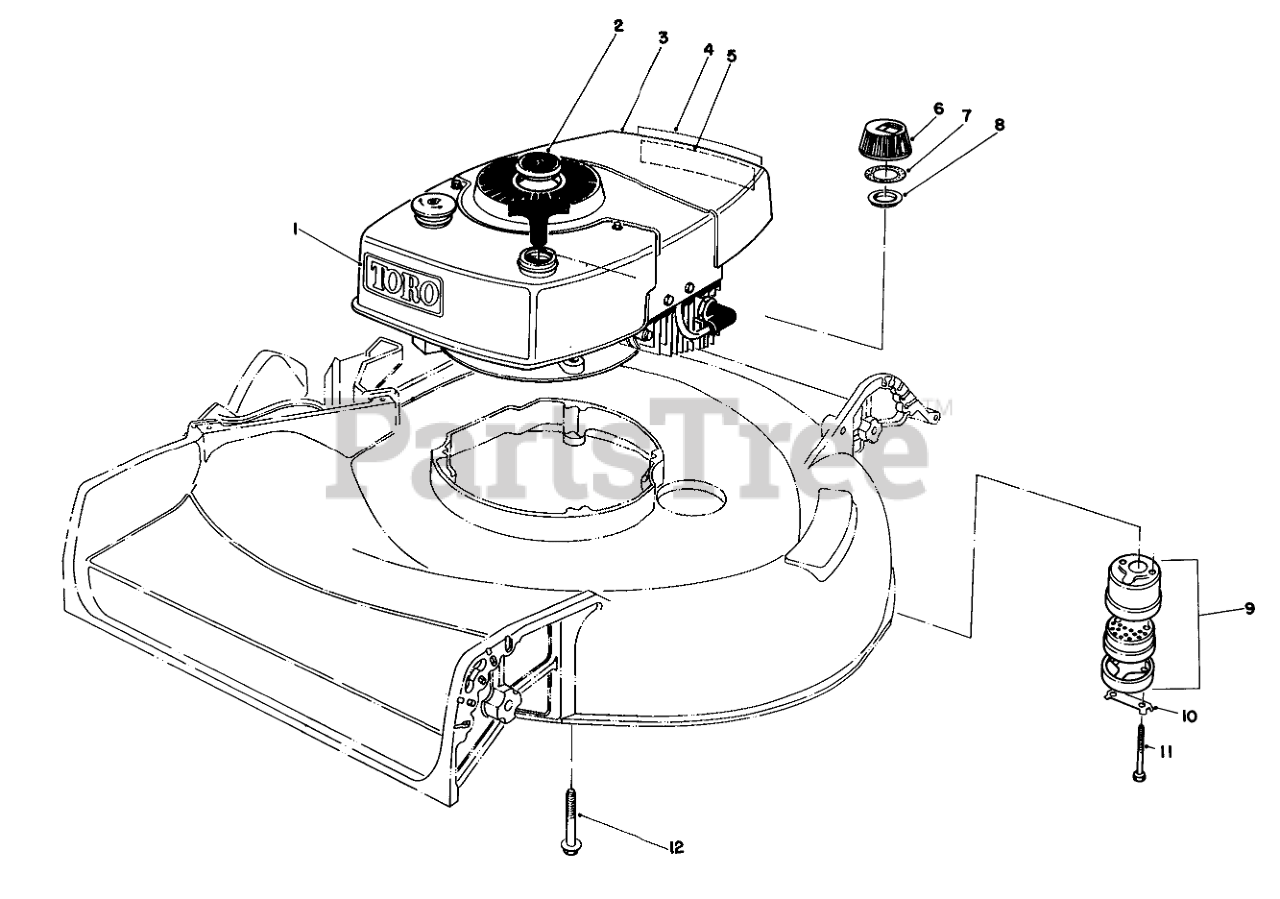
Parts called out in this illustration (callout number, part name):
1	Decal Tow
2	Plug Button
3	Engine
4	Decal-Primer
5	Decal Maintenance
6	Fuel Cap Assembly (Incl. Ref. #7 8 8)
7	GASKET
8	GAS CAP BAFFLE
9	Muffler Assembly (Incl. Ref. #10 & 11)
10	CLIP - LOCKING
11	SCREW-HH
12	3/8-16 X 2-3/4 CAPSCR
